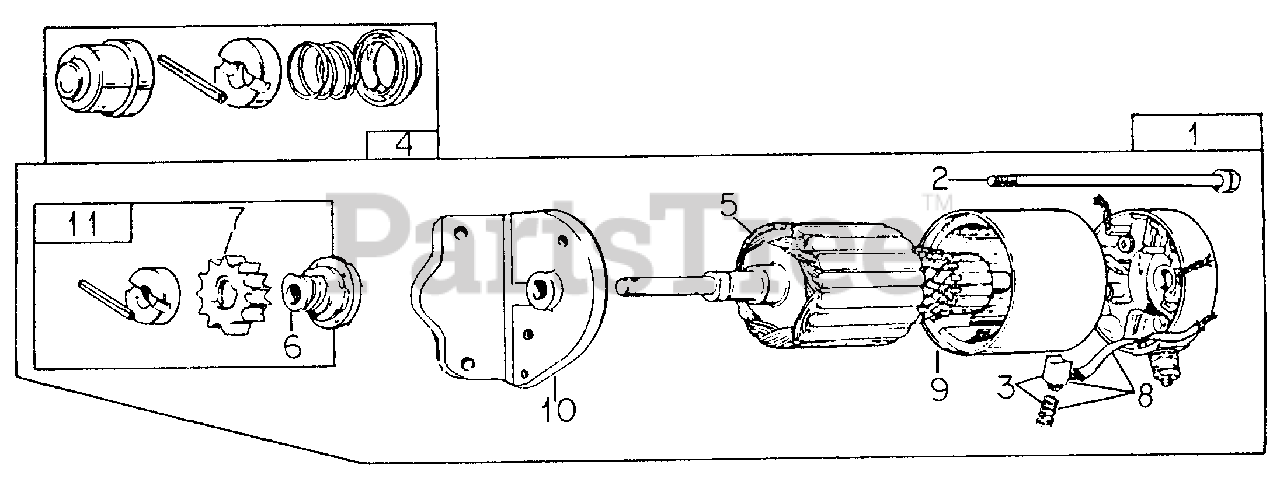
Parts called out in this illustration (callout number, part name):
1	Starter Assy
3	Set, Brush
4	Kit, Pinion Spring
5	Armature Assy
6	Clutch Assy, Starter
7	Gear, Starter Clutch
8	Cap Assy, End
9	Housing, Starter
10	Cap, Drive End
11	Drive Assy, Starter
